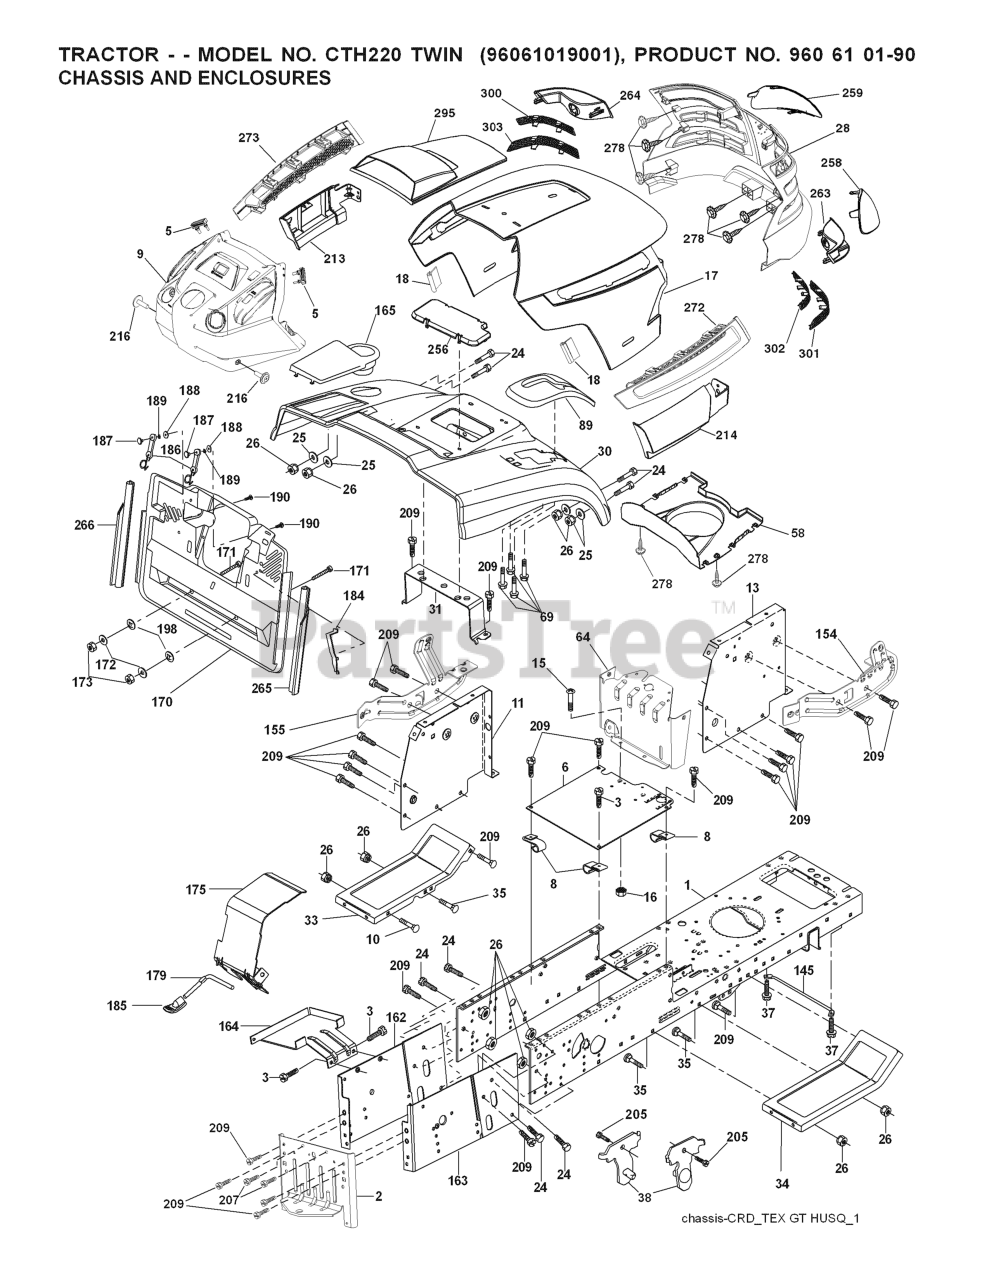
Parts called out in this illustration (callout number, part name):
2	DRAWBAR
3	SCREW 3/8-16X3/4
5	BUMPER DASH
6	PLATE
8	CLIP,INSULATOR
10	BOLT D
11	PANEL DASH LH
13	PANEL DASH RH
15	Screw, Machine, Truss Head 5/16-18 UNC x 3/4
16	NUT
17	HOOD
18	BUMPER.HOOD.TEX.HUSQVARNA
25	WASHER
26	NUT
28	GRILL.ASM.HUSQ.TG/CRD.W/TRIM
30	CONSOLE.CRD.AUTO.GRY
31	BRACKET SUPPORT FENDER
33	FOOTREST PNT LH
34	FOOTREST PNT RH
37	Screw 5/16-18 x 1/2 Hex, Self Tapping 5/16-18 x 1/2
38	BRACKET ASM PIVOT MOWER REAR
58	AIR.DUCT.HOOD.TEX.GT.HUSQ
69	SCREW.HI-LO.CONSOLE
89	CONSOLE.CRD.AUTO.GREY.2005
145	ROD.PIVOT.HOOD
162	BRACKET
163	BRACKET EXTEN CHASSIS RH CRD
165	RP.COVER.BATTERY.CRD.GREY
172	WASHER
175	DOOR TRAP
179	ROD PIVOT FBI
184	BRACKET.ACTUATOR.BAGGER.SRD
186	LATCH ASSY
187	WELDNUT
189	LOCKWASHER #10
190	SCREW
207	SCREW, 5/16-18 X 1/2
209	SCREW, 3/8-16X3/4
213	SKIRT.HOOD.SIDE.HUSQ.LH.GREY
214	SKIRT.HOOD.SIDE.HUSQ.RH.GREY
216	SCREW 14-20 X 5/8
256	COVER FENDER CRD
258	LENS.RH.TEX.GT.HUSQ.CL
259	LENS.LH.TEX.GT.HUSQ.CL
263	BEZEL.RH.TEX.GT.HUSQ
264	BEZEL.LH.TEX.GT.HUSQ
265	SEALING
266	SEALING
272	VENT.SIDE.HOOD.HUSQ.RH.GREY
273	VENT.SIDE.HOOD.HUSQ.LH.GRAY
278	SCREW
295	VENT.ASM.HOOD.TOP.TEX.
300	INSERT.HEX.GRILL.HUSQ.
301	INSERT.HEX.GRILL.HUSQ.GREY
302	INSERT.HEX.GRILL.HUSQ.
303	INSERT.HEX.GRILL.HUSQ.
